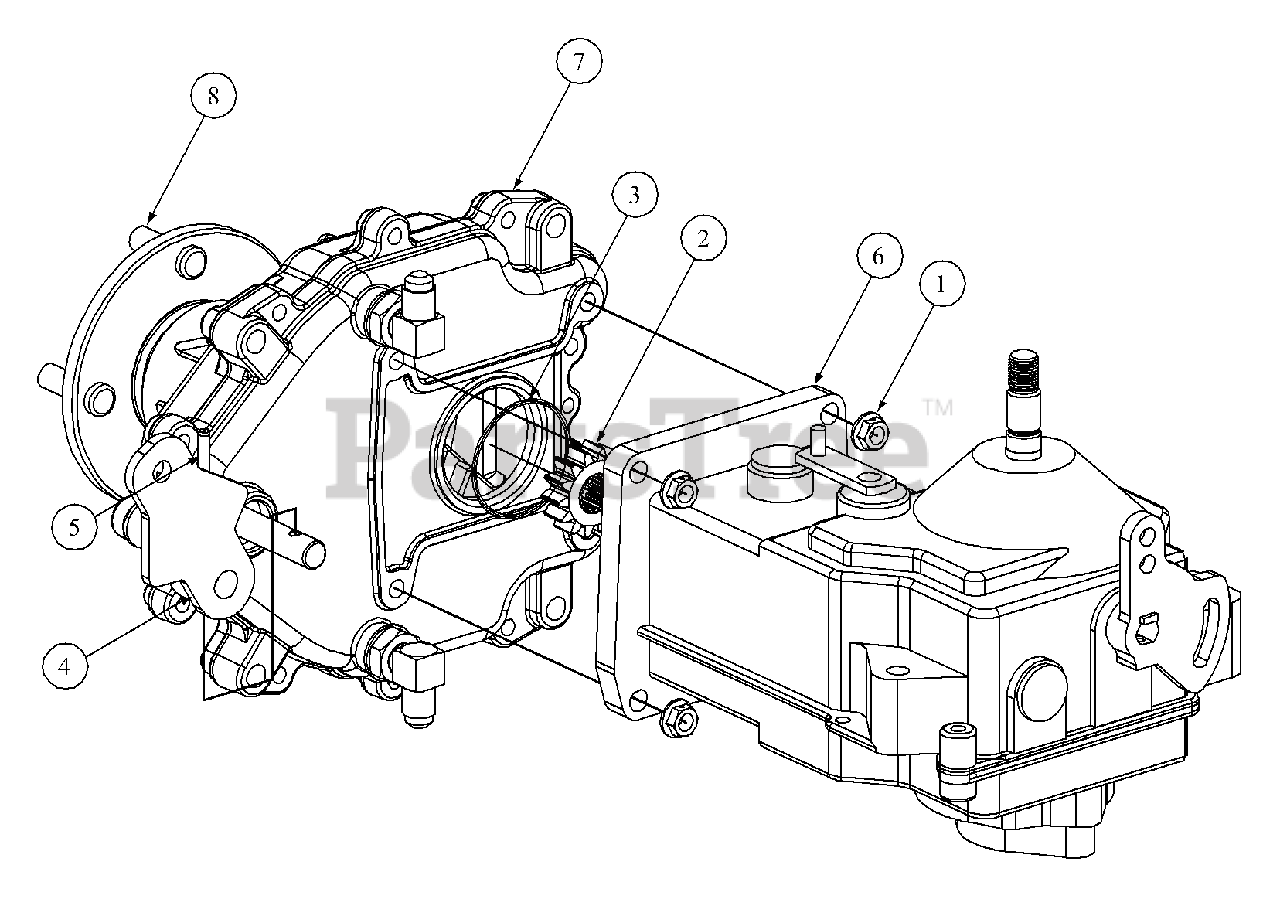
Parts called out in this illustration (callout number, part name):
1	Lock Nut , Hex Flange 5/16-18
2	Gear,Spur, 14T
3	O-Ring, 2.00 x .070
4	Lever, Brake, Park
5	Pin, Spirol, 3/16 x 1.25 HD
6	Pump, Hydro
7	Transmission Assembly
8	rib Neck Stud, 1/2-20
